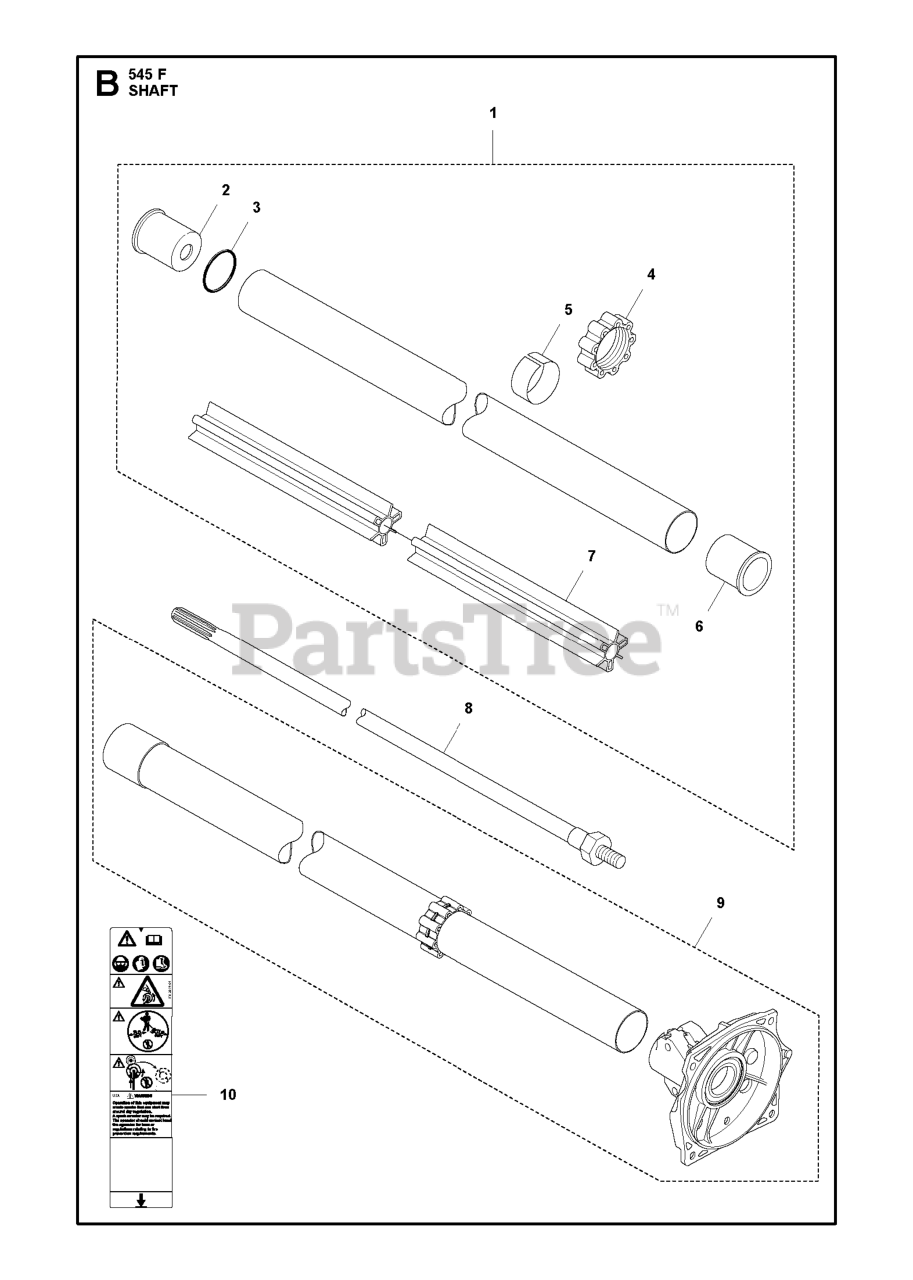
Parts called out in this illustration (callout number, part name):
1	Tubes
2	SPACER SLEEVE
4	MOVEMENT LIMITER
6	SPACER SLEEVE
7	BEARING SHAFT
8	SHAFT
10	LABEL WARNING TRIMMERS AND BRU
